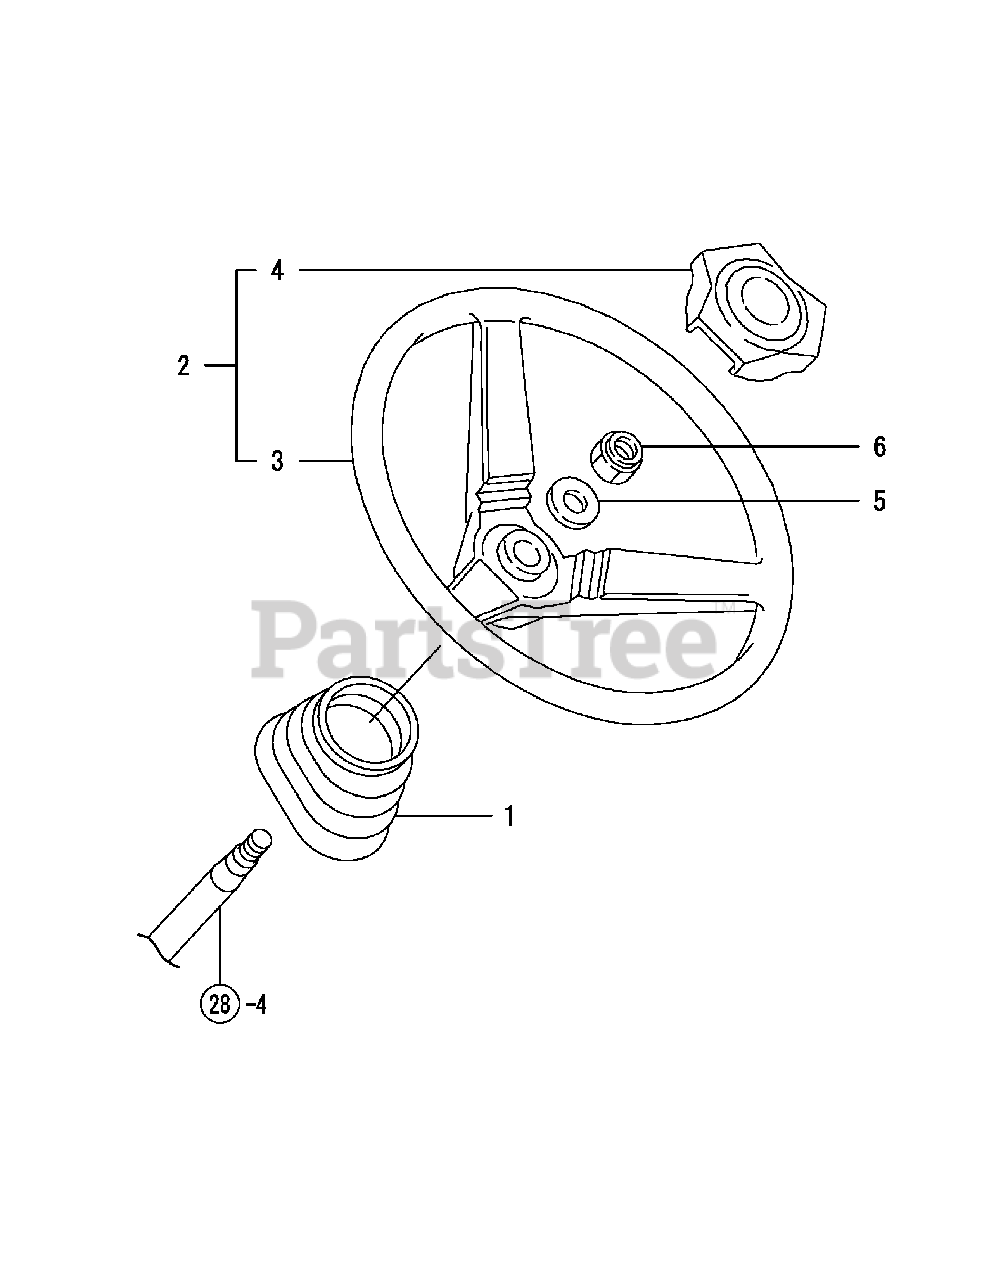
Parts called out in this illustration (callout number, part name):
2	WHEEL, STEERING CMP
3	WHEEL, STEERING
4	CAP STEERING CMP
5	WASHER 16,POLISHED
